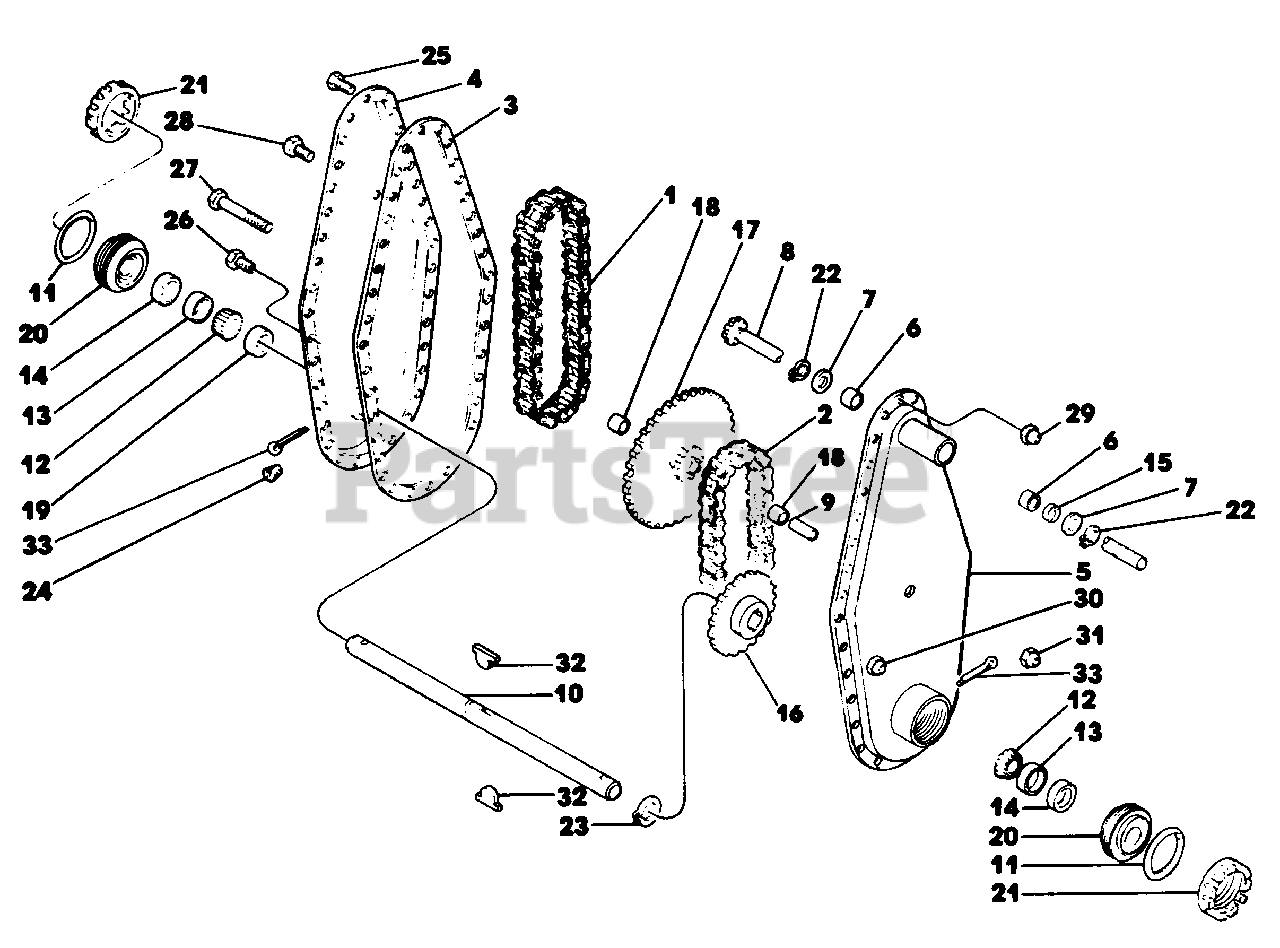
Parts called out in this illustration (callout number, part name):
1	Chain-Uppers
2	Chain-Lower
3	Gasket
4	Chain Case Assembly
5	Chain Case Assembly L.H. w/Bearings
6	Bearing
7	Washer
8	Input Shaft
9	Idler Sleeve
10	Tine Shaft
11	O-Rings
12	Bearing Cone
13	Bearing Cone
14	Oil Seal
15	Seal Power Shaft
16	Sprocket
17	Idler Sprocket Assembly w/Bearing
18	Bearing
19	Spacer
20	Bearing Adjustment
21	Adjustment Plug Lock Ring
22	Snap Ring
23	Snap Ring
24	Pipe Plug
25	Cap Screw Hex Hd. 1/4-20 x 3/4 Plated, Grade 5
26	Cap Screw Hex Hd. 5/16-18 x 3/4 Plated, Grade 5
27	Cap Screw, Hex Hd. 3/8-16 x 2-1/2" Plated, Grade 5
28	Cap Screw, Hex Hd. 1/2-20 x 3/4 Plated, Grade 5
29	Nut, Hex Cone Lock 1/4-20 Plated
30	Nut, Hex Cone Lock 5/16-18 Plated
31	Nut, Hex Cone Lock 3/8-16 Plated
32	Key, Hypro 1/4 x 7/8 Grade 5
33	Pin, Cotter 1/8 x 3/4 Plated
